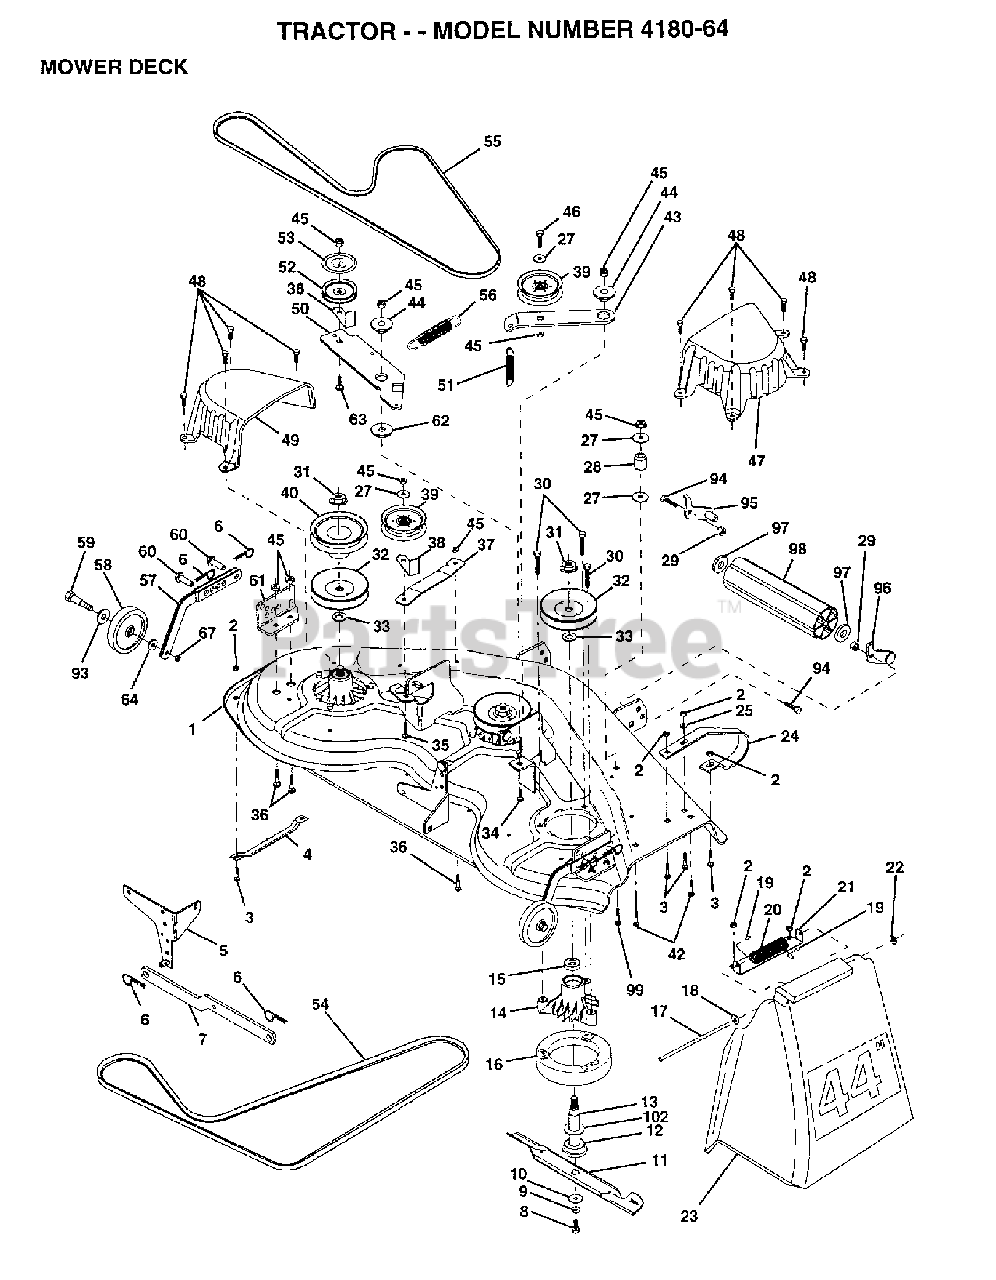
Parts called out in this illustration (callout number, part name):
2	LOCKNUT
3	BOLT.5/16-18.
4	RUNNER LH
5	BRACKET SWAY BAR
6	RETAINER SPRING
8	BLADE BOLT
10	WASHER.BLADE
11	44" BLADE-HI PERFORMANCE
12	BEARING.BALL.#6204.(MANDREL)
13	SHAFT.ASM.W/BEARING
14	HOUSING.MANDREL
17	ROD-HINGE T
18	WASHER
19	CAP-SLEEVE LT
20	DEFLECTOR SPRG T
21	BRACKET, DEFLECTOR
22	NUT PUSH M
23	DEFLECTOR SHIELD
24	RUNNER-RH YTV
25	WASHER M
28	IDLER SPRING SPACER
29	NUT
30	Hex Washer Head Bolt, .313-18 X 1.19
32	PULLEY/MANDREL
33	WASHER
35	BOLT
37	STIFFENER ARM
39	IDLER-FLAT GT
40	PULLEY.DRIVEN.44"
42	BOLT
43	ARM.IDLER.SEC.44"
46	LOCKNUT
46	BOLT
47	COVER MANDRELL
48	SCREW.1/4-20X5/8
49	COVER.MANDREL.LH.44"
50	ARM.IDLER.PRIMARY
51	SPRING.SEC.44"VEN
52	PULLEY IDLER
53	SHIELD IDLER
55	BELT
57	BAR.ASM.GUAGE.WHEEL
58	GUAGE WHEEL GT
59	BOLT
60	PIN.CLEVIS
61	BRACKET.GUAGE.WHEEL
63	BOLT.3/8-16X1.50
64	WASHER
67	LOCKNUT
95	Roller Bracket Assembly, LH
97	BOLT
98	MANUAL, OPERATOR
99	BOLT
102	WASHER FELT
